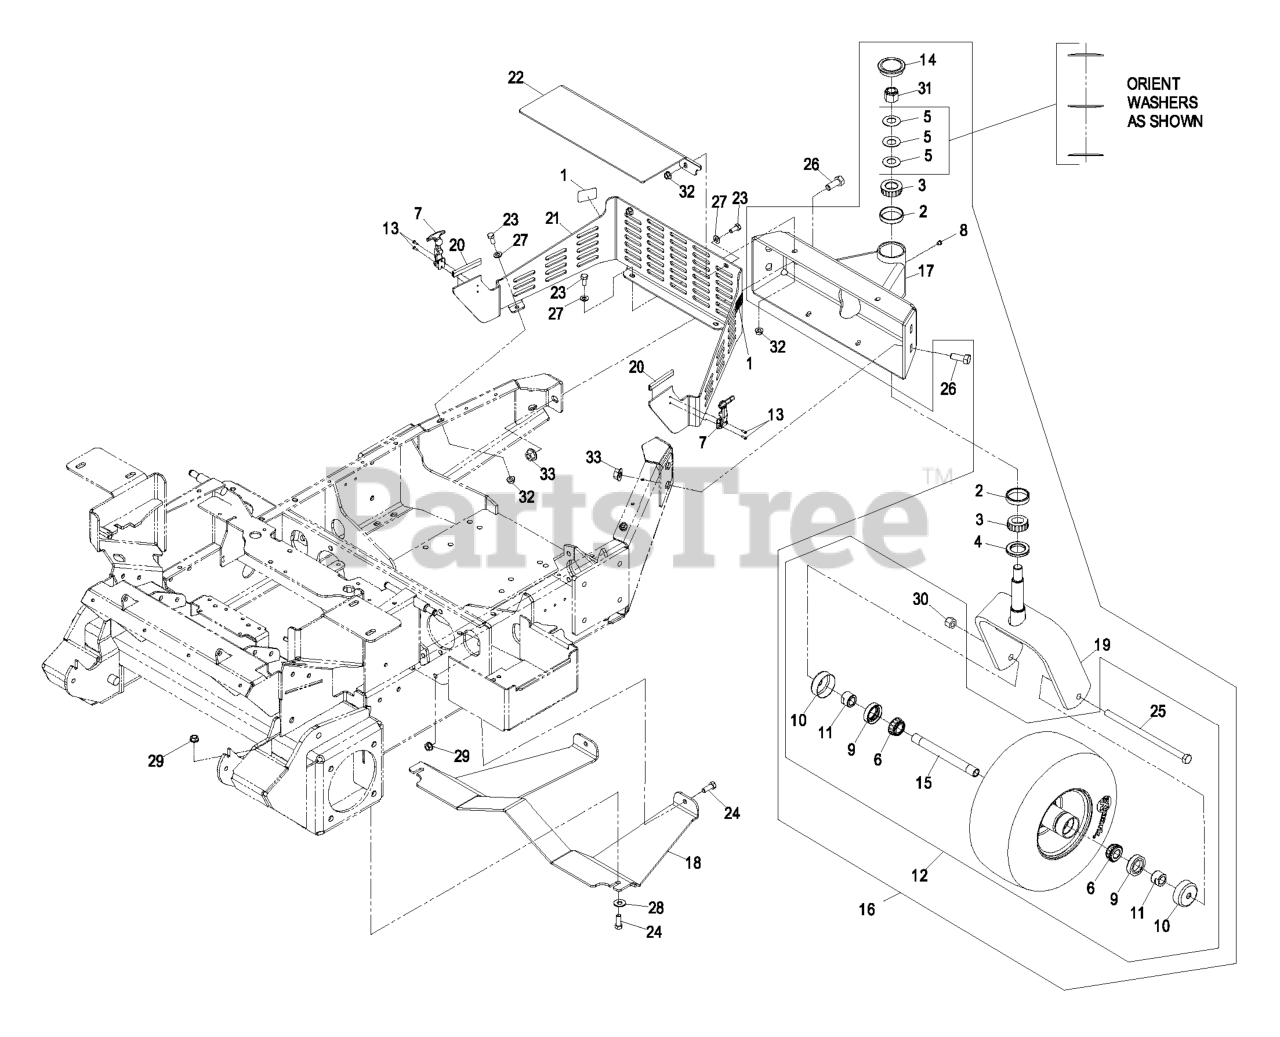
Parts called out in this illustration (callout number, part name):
2	CUP-BEARING
3	Cone-Bearing Tapered Roller
4	SEAL-GREASE
5	WASHER-BELLVILLE
6	BEARING-CONE, TAPERED ROLLER
7	LATCH-RUBBER
9	SEAL-CASTER
10	GUARD-SEAL
11	SPACER-NUT
14	CAP-GREASE
16	ASM,SINGLE TAILWHEEL
20	STRIP-SEAL
21	ASM,FMZ REAR GUARD
22	COVER,MUFFLER FMZ
23	SCREW-HH
24	SCREW-HH
25	SCREW-HH
26	SCREW-HH
27	WASHER-PLAIN
28	WASHER-FLAT
29	NUT-HHF, WHIZ
30	NUT-LOCK, NI
31	NUT-LOCK, NI
33	NUT-HHF
